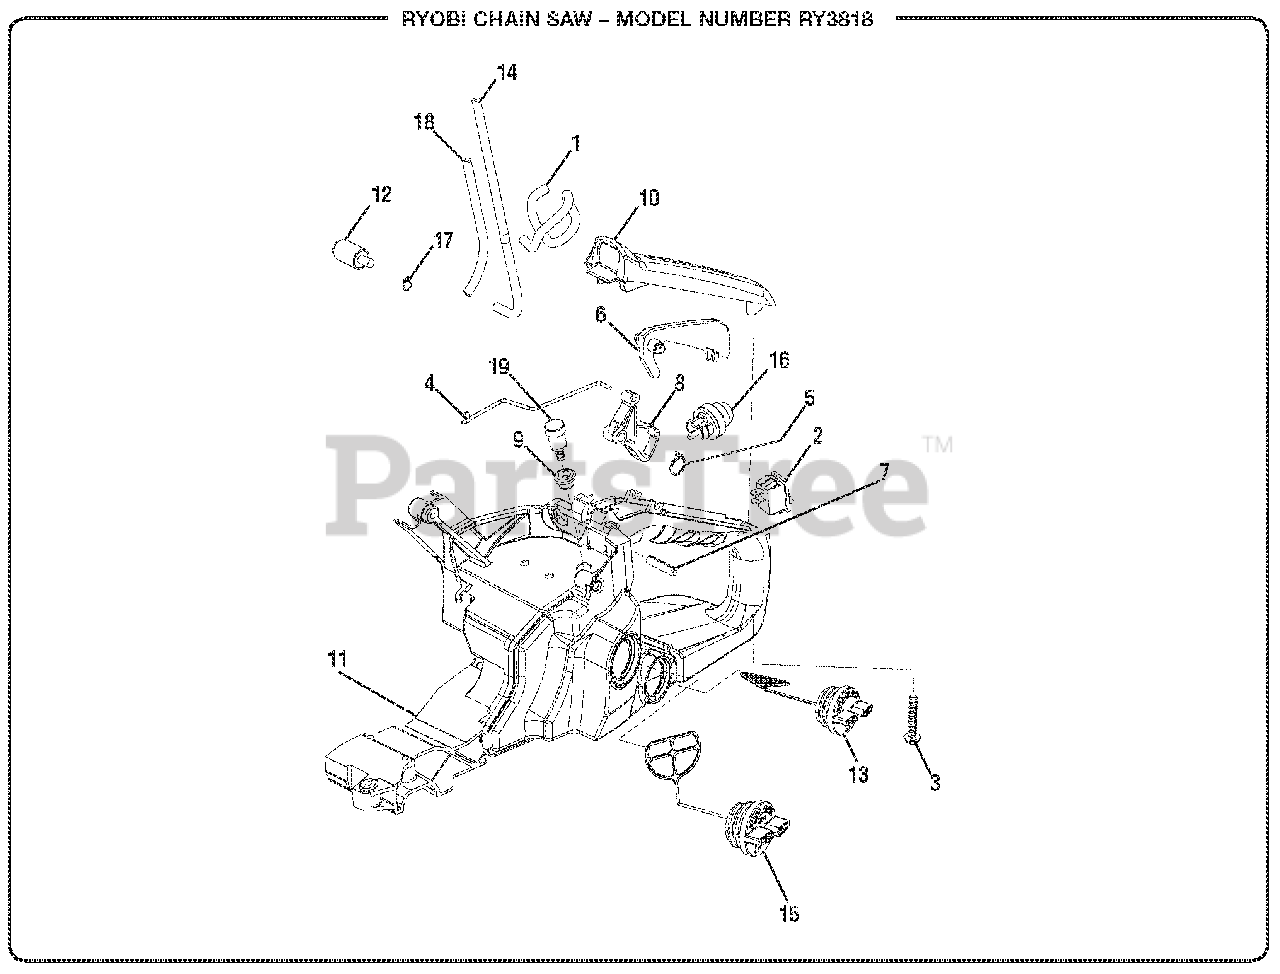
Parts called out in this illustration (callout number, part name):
1	Fuel Hose (Primer Assembly to Carburetor, 160 mm)
3	Screw (M5 x 27 mm, T25 Torx Pan Hd.)
4	Throttle Rod
5	Throttle Spring
6	Safety Rocker Arm
7	Spring Pin
10	Grip Cover
12	Fuel Filter Assembly
13	Chain Oil Cap
14	LP-1500 Tubing (205.00 mm)
15	Fuel Cap Assembly
16	Primer Assembly
17	Hose Clip
18	Fuel Hose (Primer Assembly to Tank, 153 mm)
19	Fuel Breather Assembly
